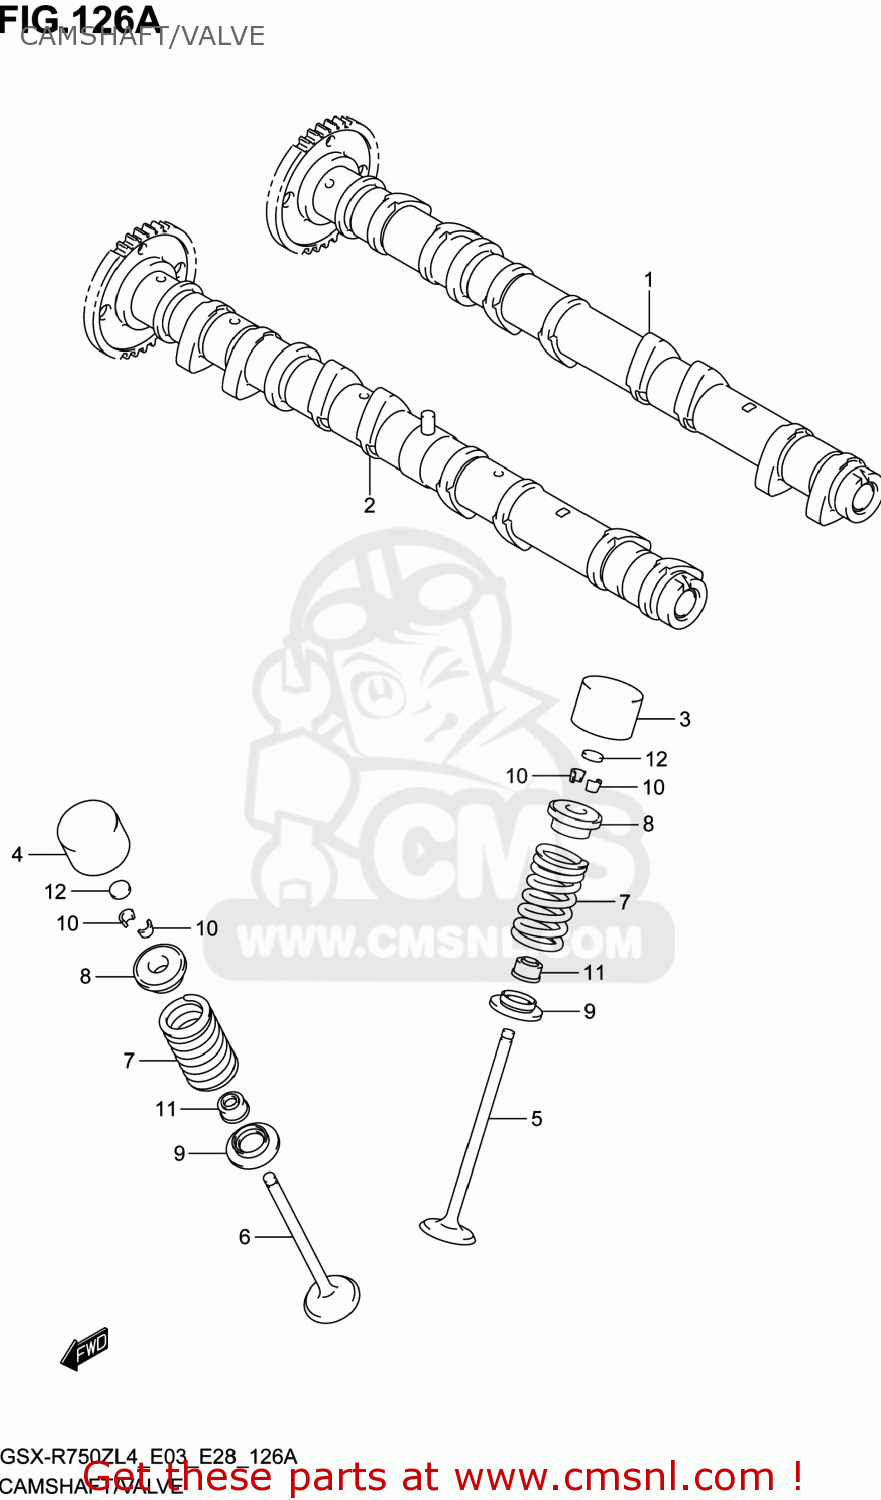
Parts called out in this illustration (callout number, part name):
1	CAMSHAFT,INTAKE
2	CAMSHAFT,EXHAUST
3	TAPPET
4	TAPPET,EXHAUST
5	VALVE,INTAKE
6	VALVE,EXHAUST
7	SPRING,VALVE
8	RETAINER,VALVE SPRING
9	SEAT,VALVE SPRING
10	COTTER VALVE
11	SEAL,OIL(4.5X10X8)
12	SHIM,TAPPET
13	SHIM SET,TAPPET
14	CASE,TAPPET SHIM
